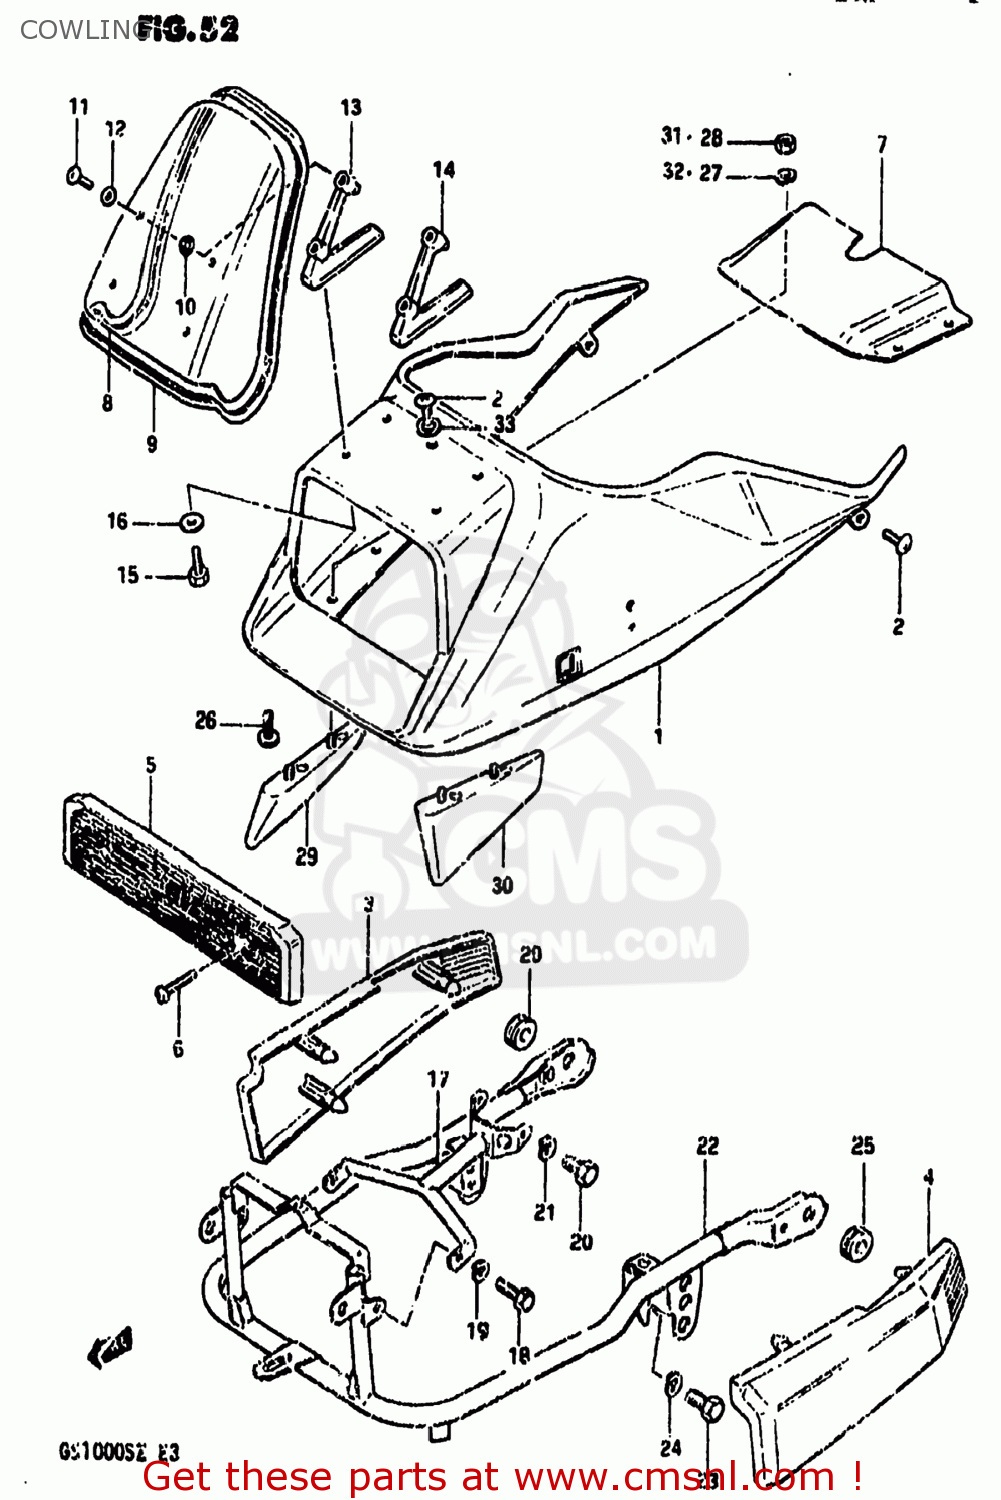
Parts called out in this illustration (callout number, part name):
1	BODY COWLING
2	SCREW 6X12
3	COVER, RH (SILVER)
4	COVER, LH (SILVER)
5	COVER,COWLING LOWER
6	SCREW
7	COVER,COWLING LOWER FR
8	WINDOW,COWLING
9	MOLD,COWLING
10	CUSHION
11	SCREW
12	WASHER(5.2X11X1)
13	BRACE,COWLING WINDOW RH
14	BRACE,COWLING WINDOW LH
15	BOLT
16	WASHER(6.5X16X1.2)
17	BRACKET,COWLING UPPER
18	BOLT
19	LOCK WASHER
20	BOLT
21	LOCK WASHER
22	BRACE,COWLING RR
23	BOLT 8X12
24	LOCK WASHER
25	CUSHION
26	SCREW
27	LOCK WASHER
28	NUT
29	WING,COWLING RH
30	WING,COWLING LH
31	NUT
32	LOCK WASHER
33	WASHER
